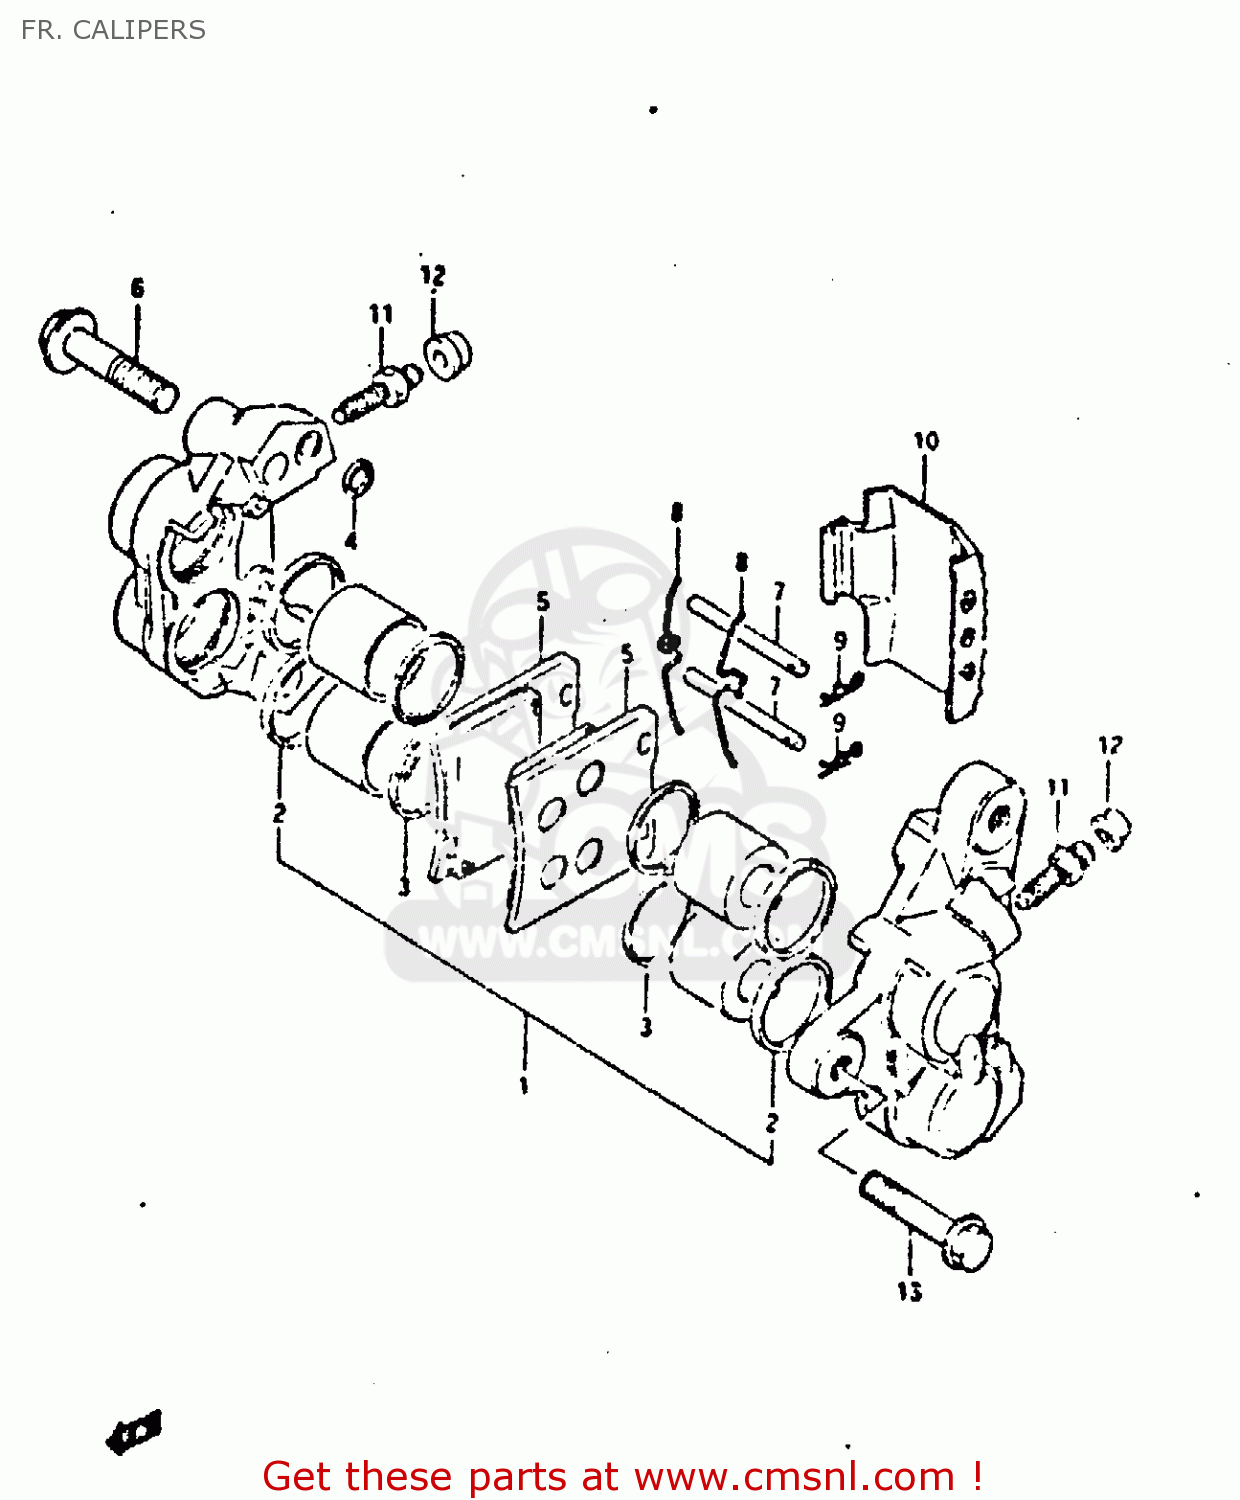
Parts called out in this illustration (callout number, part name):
1	PISTON SET
2	SEAL,PISTON
3	SEAL,WIPER
4	SEAL,JOINT
5	PAD SET
6	BOLT,HOUSING
7	PIN,PAD
8	SPRING
9	CLIP,PAD PIN
10	COVER,CALIPER
11	BLEEDER
12	CAP,BREATHER
13	BOLT
